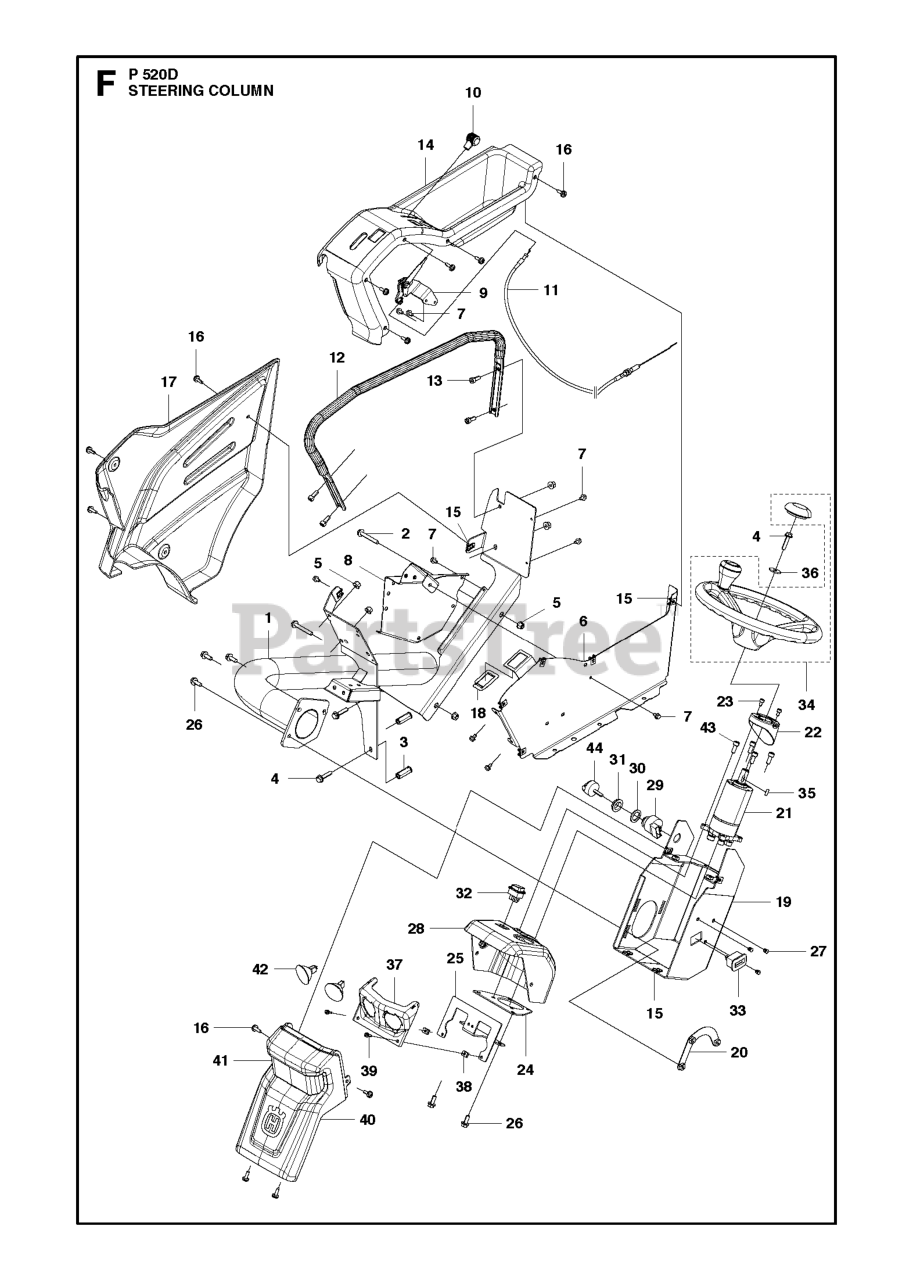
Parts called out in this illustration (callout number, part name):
2	SCREW EHHFM
4	SCREW EHHFM
5	NUT FLANGE
23	SCREW MC6S 6X10
27	INSERT PIPE END
